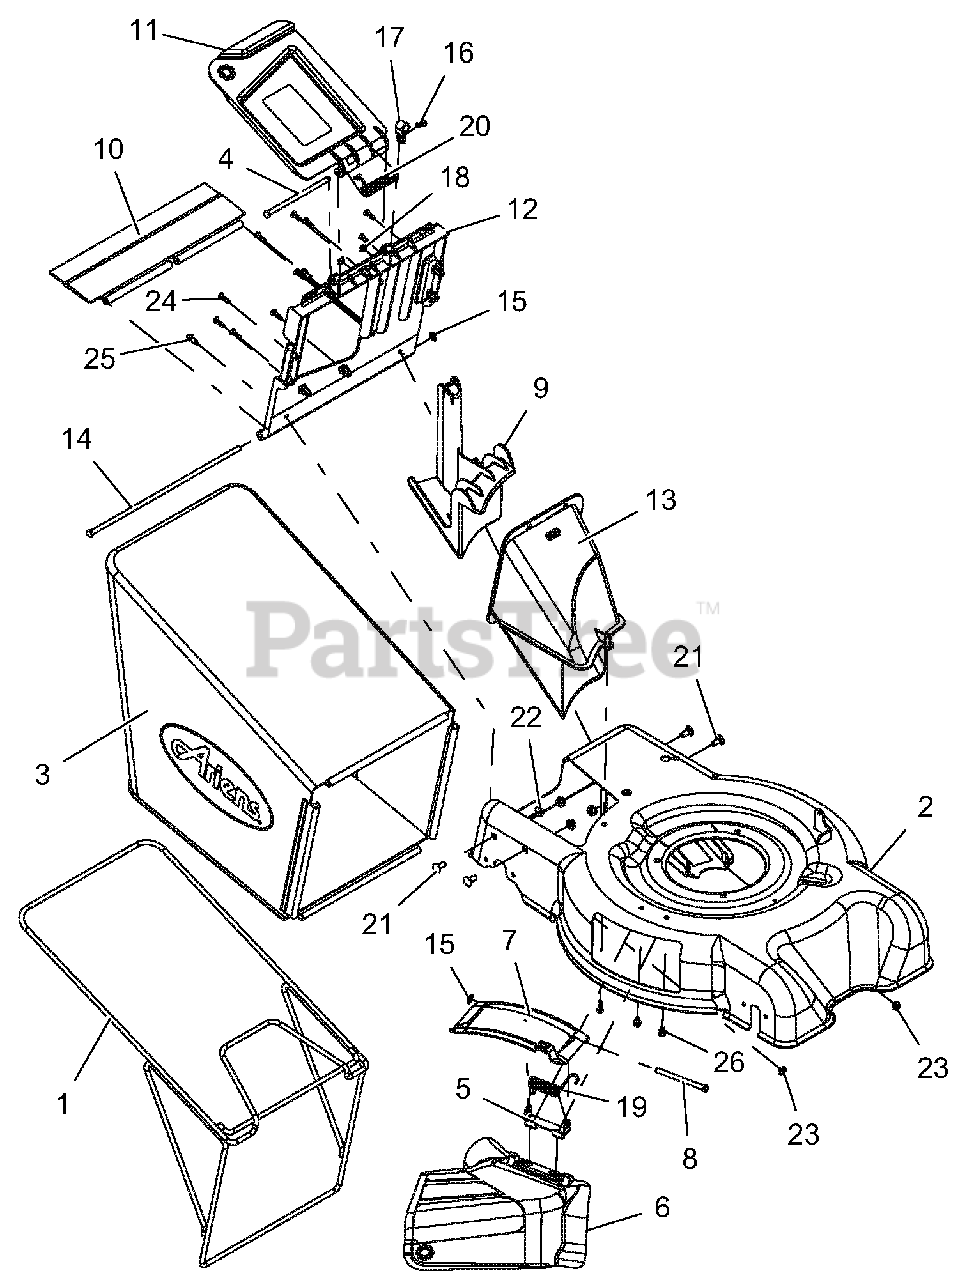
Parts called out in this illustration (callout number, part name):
1	FRAME, BAG
2	DECK, RAZOR W/ SAFETY DECALS
3	BAGGER, ARIENS LM
4	PIN, 5/16 X 5.80"
5	BRKT, HINGE LM
6	CHUTE, SIDE DISCHARGE - LM
7	COVER, SIDE DISCHARGE - LM
8	PIN, HINGE
9	PLUG, MULCH
10	GUARD, REAR
11	REAR DOOR W/ SAFETY DECAL
12	HANGER, BAG
13	CHUTE, REAR DISCHARGE LM
14	ROD, REAR GUARD
15	NUT-PUSH .312
16	PIN-HAIR INT .08X.18X1.18 YWZC
17	CLAMP, LM CABLE
18	PLUG,5/16 HOLE,.125 MATL PLSTC
19	SPRING, DOOR HINGE
20	SG-TORS .120X.68X3.09
21	@BLT-RDHDSQNK .31-18X.75 G5YZ
22	@NUT-LK-TOP-FLG .31-18 YWZC
23	@NUT-LK-TOP-FLG .25-20 YWZC
24	SCR-TAP 12-14X.75PLSTITE @BLZC
25	@SCR-TAP .25-20X.62 HWH TR YWZ
26	@SCR-TAP .25-20X.37 HWH YWZ TR
